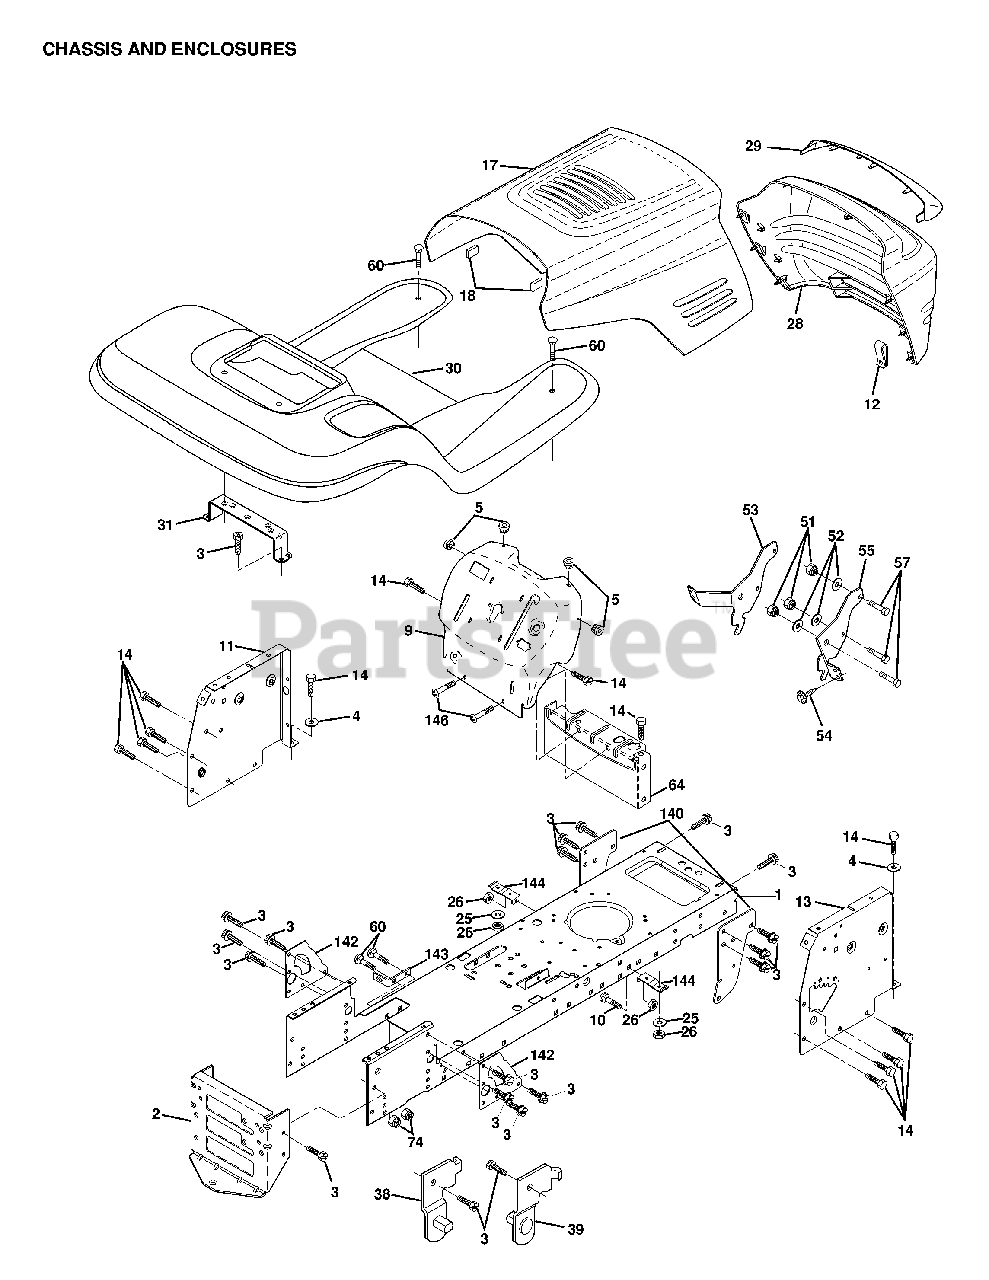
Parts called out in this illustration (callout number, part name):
1	CHASSIS WELDMENT
2	STRETCH DRAWBAR
3	SCREW
9	BOLT D
10	BOLT D
11	PANEL PNT DASH LH
13	PANEL DASH RH
20	PLATE MTG
23	GROMMET T
25	WASHER
26	NUT
38	BRACKET LH PIVOT
39	BRACKET RH PIVOT
51	LOCKNUT
57	BOLT
58	AIR DUCT P/L/LT
64	DASH LOWER
74	LOCKNUT
140	BRACKET CHASSIS FRONT
142	PLATE REINFORCEMENT
143	BRACKET, SWAY BAR
144	BRACKET FOOTREST
145	AXLE, BRACE
146	SCREW TORX HD 5/16X18
